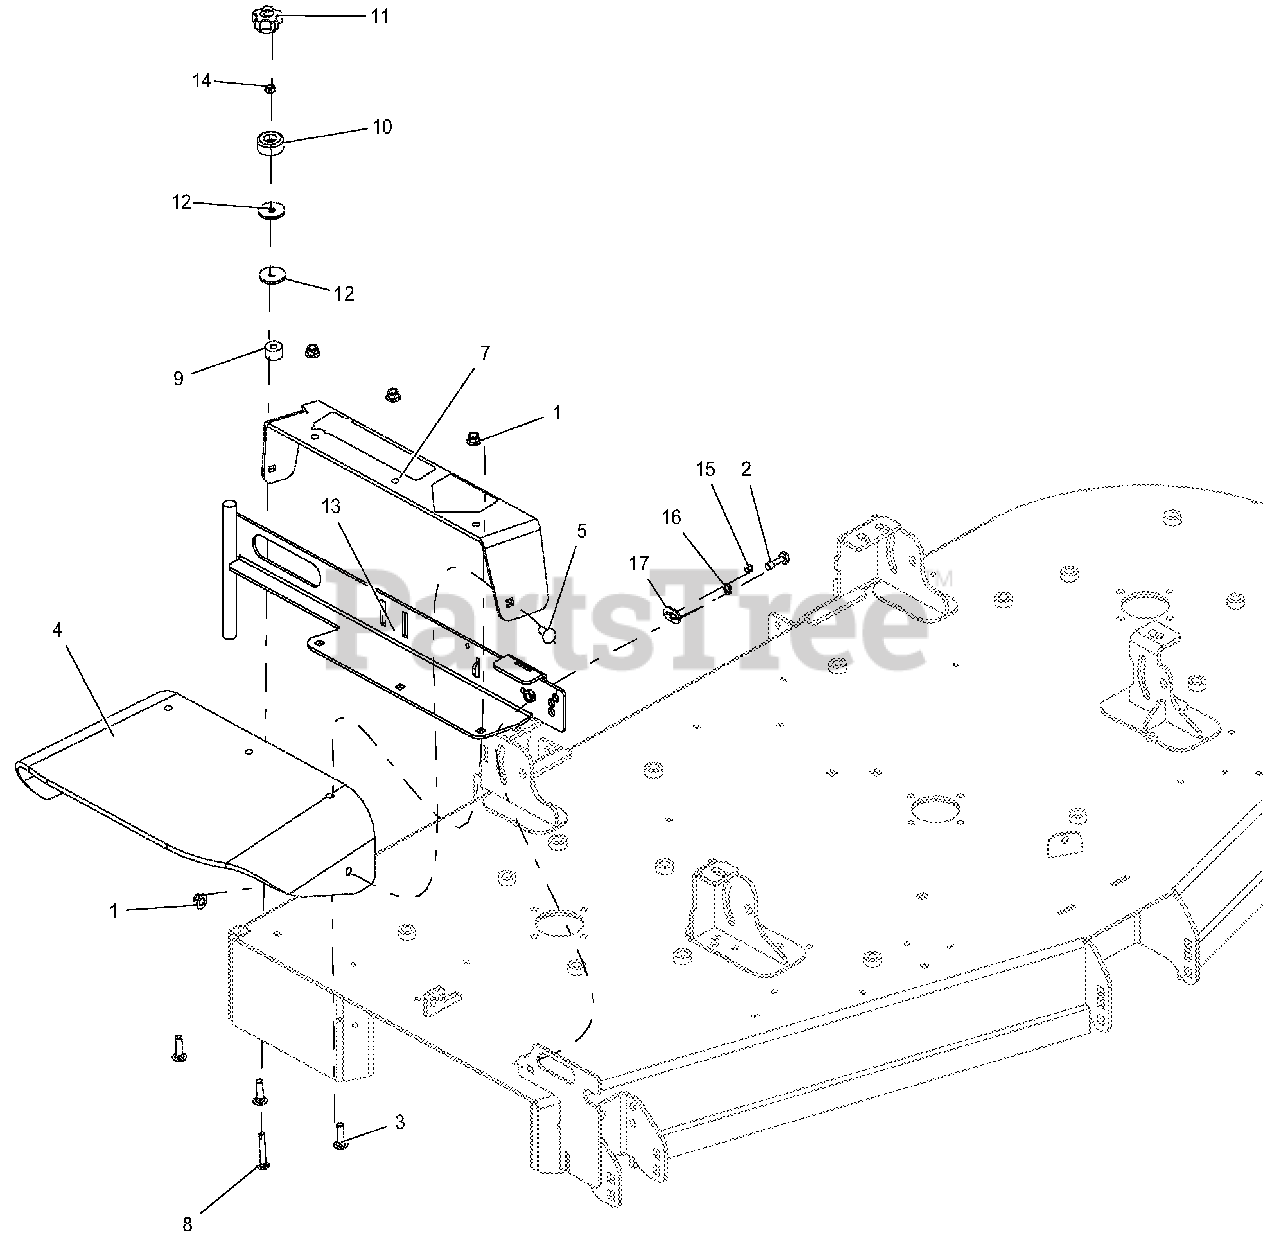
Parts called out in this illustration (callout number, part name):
1	NUT-LK-NYL-FLG .38-16 YWZC
2	BLT-HEX .38-16X1.25 GR5 CAP .37
3	BLT-RDHDSQNK .38-16X1.25 G5 YWZC
4	CHUTE, RUBBER DISCHARGE
5	BLT-RDHDSQNK .38-16X1.00 G5 YWZC
7	DISCHARGE CHUTE SUPPORT W/SAFETY DECAL-RED
8	BLT-RDHDSQNK .31-18X2.0 FTH G5 Y
9	SPACER .390X1.000X.562
10	BUMPER, RECESSED 1.50 X .63 W/.31 HOLE
11	KNOB, CLAMPING
12	WSHR-FL-STL .380X1.50X.125 YWZC
13	WLDMT, 72" DISCH CHUTE MTG-CE
14	NUT-LK-CTR .31-18 YWZC
15	RVT-POP .187x.250 (#64) YWZC
16	LOCK, WSHR-EXT 0.391 X 0.628 X 0.036 YWZC
17	KEEPER, BOLT
